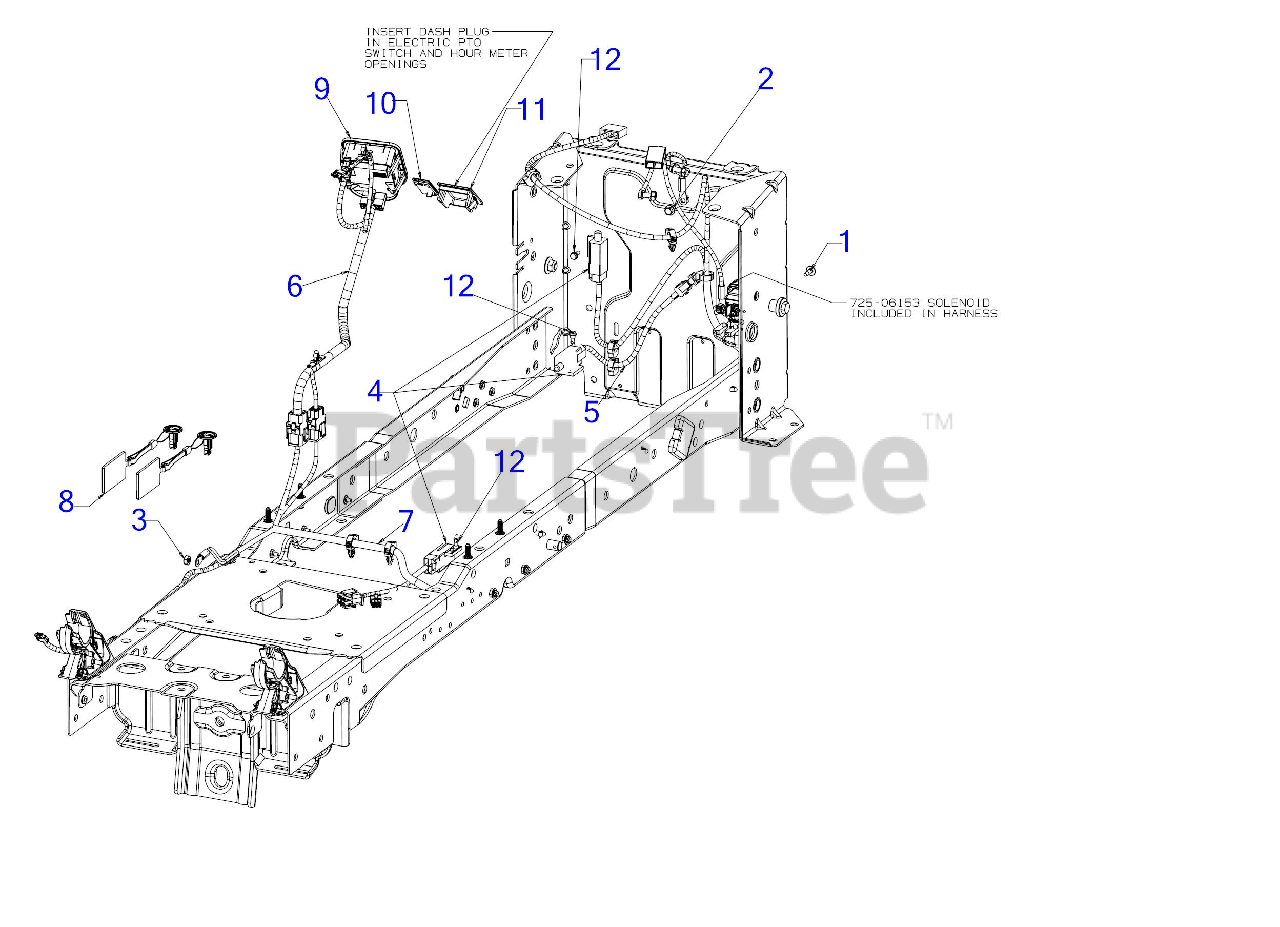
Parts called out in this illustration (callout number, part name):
1	SCREW M6-1 x .625
2	SCREW 1/4-20X.625
3	HEX NUT 1/4-20
4	INTERLOCK SWITCH (NO/NC)
5	REVERSE HARNESS
6	DASH HARNESS M-PTO/PBS/EFI/RMC
7	MAIN HARNESS M-PTO/PBS/EFI
8	PBS KEY
9	MODULE-PBS/HRMTR/SVC MNDR/BT
11	DASH HOUR METER PLUG
12	SHOULDER SCREW
